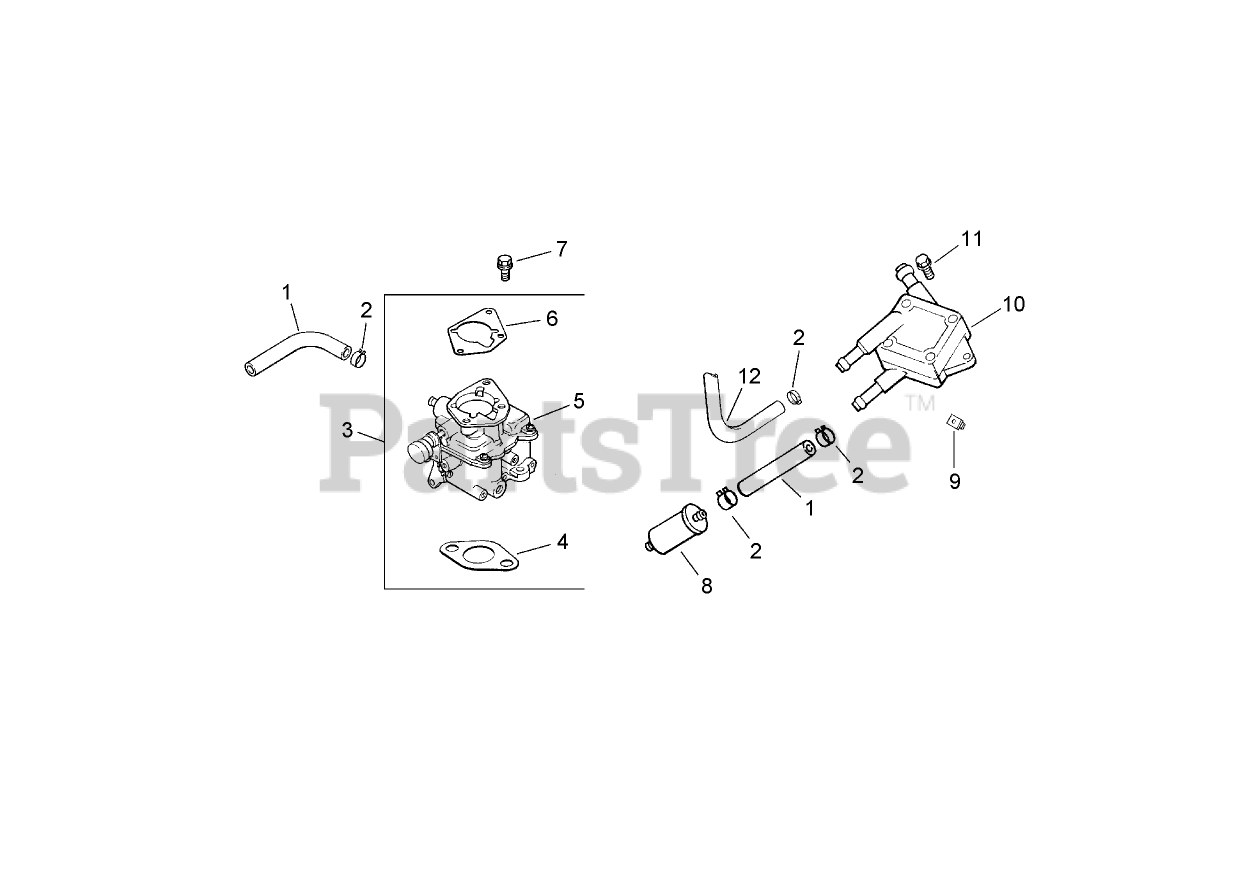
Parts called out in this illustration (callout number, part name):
1	Line-Fuel (9.5)
2	CLAMP-HOSE, SPRING (1/2)
3	Carburetor Kit (Includes 4-6)
4	Gasket-Carburetor
5	Carburetor ASM (For information only not available separately) (Service with: 24 757 01-S, 24 757 02-S, 24 757 03-S, 24 757 08-S, & 24 757 09-S)
6	GASKET-BASE, AIR CLEANER
7	SCREW-FLANGE (M6X1.0X30)
8	Filter-Fuel
9	Nut-Plastic
10	PUMP-FUEL
11	SCREW-TAP (M6X1.7X18)
12	Line-Fuel, Flexible (15.5)
